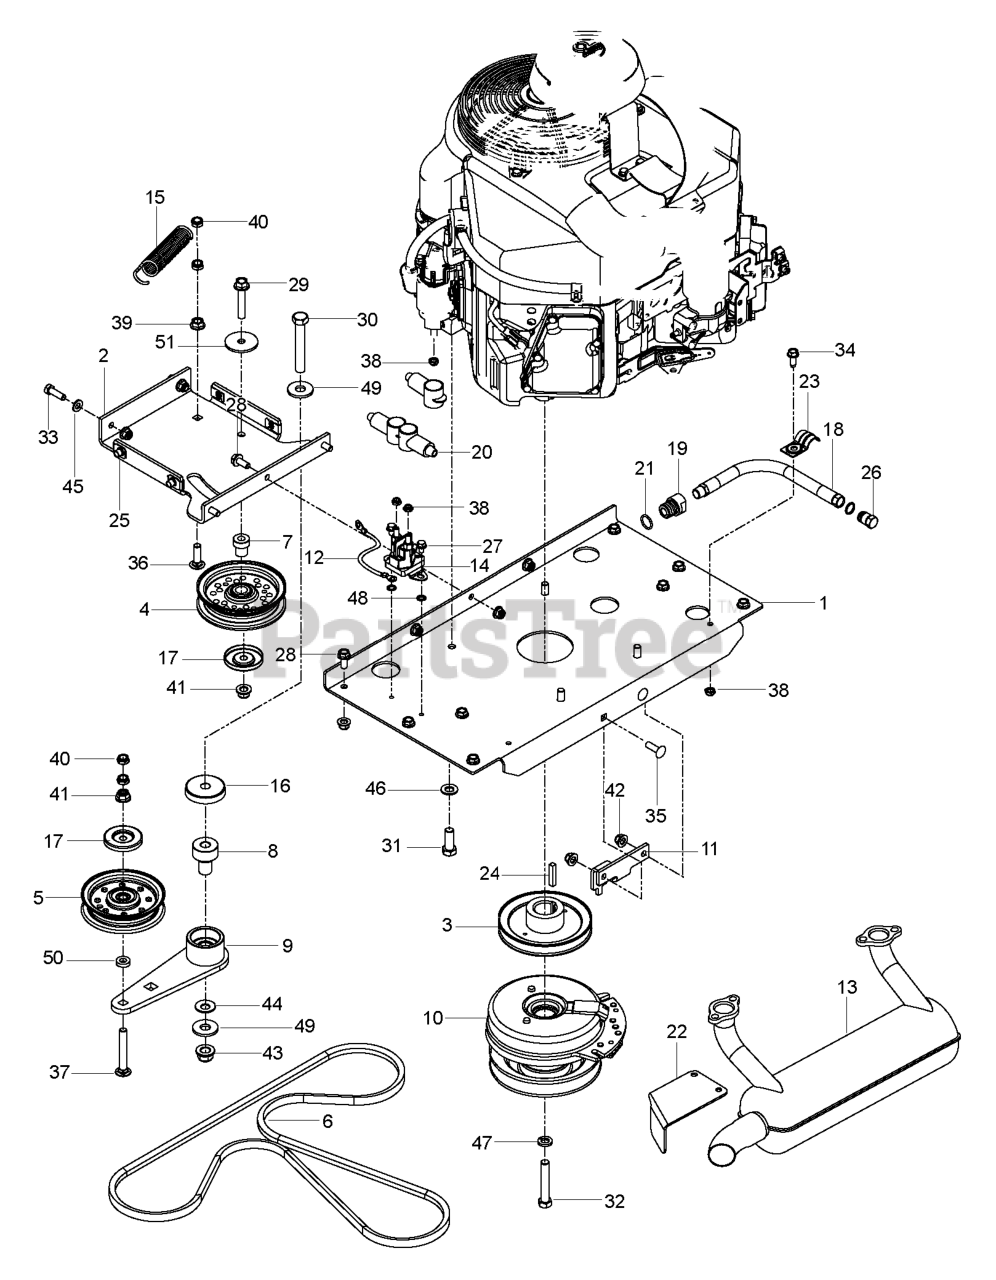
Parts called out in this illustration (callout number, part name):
1	PLATE, ENGINE, BLK
2	PLATE, IDLER, BLK
3	PULLEY, V, 1.125 BORE
4	IDLER PULLEY
5	FLAT IDLER PULLEY
6	BELT, HYDRO, 3400
7	PIVOT, IDLER
8	PIVOT, BEARING
9	ARM, IDLER, STEEL, W/BGS
10	CLUTCH 200 FT LB
11	STOP, CLUTCH, BLACK
12	CABLE POSITIVE
13	MUFFLER.26HP.KAW.FX651V-730V
15	SPRING, PUMP
16	SHIELD, DUST
17	DUST SHIELD
18	HOSE.ASSEMBLY.OIL.DRAIN
19	ADAPTER, OIL DRAIN
22	SHIELD MUFFLER
24	KEY, 1/4 SQ X 1 1/4
25	U-CLIP 5/16-18 NUT RETAINER
26	HHFS 3/8-16 X 2.0 GD 5
27	HHFS 5/16-18 X 3/4
28	HWST 1/4C X 3/8
29	HCS 1/2C X 3 1/4
30	4CS 3/8C X 1 SERRATED HEAD
31	HCS 3/8-16X1.GRD.5.ZD
32	BOLT 7/16F X 2 1/2
33	HCS 5/16C X 1
34	HCS 1/4-20.
35	RHSSNB 5/16C X 1.0
36	RHSNB 3/8-16 X 1-1/4
37	RHSNB 3/8-16 X 2.75
38	JAM NUT 1/4C (2 2 PW01)
39	NUT 3/8C WHIZ
40	NUT HEX 3/8-16 NYLON, THIN
41	NUT 3/8-16 HEX FLG NYLOC ZD
42	5/16-18 NYLOC FLANGE NUT
43	NUT, 1/2-13 HEX FLG NYLOC ZD
44	CONTACT BELLSPR 1/2
45	FLAT WASHER 5/16 SAE
46	WASHER, 3/8 DISC SPRING SPEC
47	WASHER 7/16 LOCK
48	WASHER 1/4 INT TOOTH
49	WASH USS FLAT 1/2
50	WASHER 3/8 X 3/4 X .187 TK
51	WASHER, 3/8 SPEC
